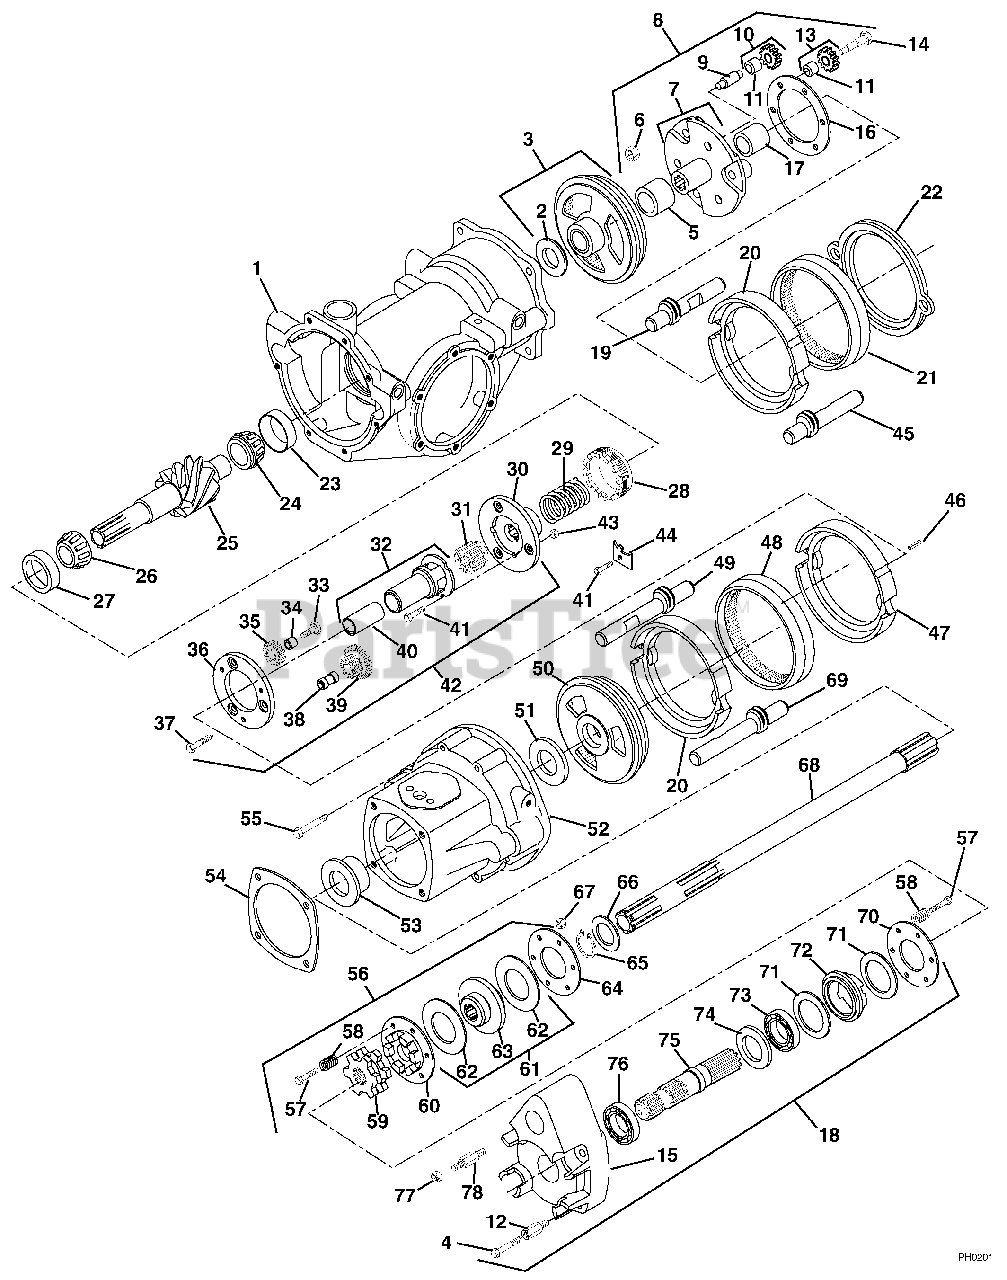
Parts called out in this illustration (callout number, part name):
1	Transmission Housing
2	Plate-Rear Thrust
3	Assembly-Ring Gear & Bushing
4	Bolt-Hex .50-13 x 1 Grade 5
5	Bushing-Sleeve 1.125 x 1.502 x 1.312
6	Nut-Locking .312-18 x .265
7	Assembly-Planet Gear Carrier
8	Assembly-Hi-Lo Planetary
9	Pin-Hi-Lo Orbit Gear
10	Assembly-Internal Orbit Gear
11	Bushing-Sleeve .500 x .627 x .465
12	Stud-Quick Hitch
13	Assembly-External Orbit Gear
14	Bolt-Orbit Gear
15	Casting-Quick Hitch
16	Spacer-Pin
17	Bushing-Sleeve .737 x .877 x .683
18	Quick Hitch Assembly
19	Rod-Rear Right Hand Clutch Slide
20	Assembly-Clutch Cup
21	Gear-Rear Ring
22	Spacer-Rear
23	Bearing-Cup 2.328 x .465
24	Bearing-Cone 1.25 x .66
25	Weldment-8-Lead Worm (114, 115, 117, 119, 307, 309, 312)
25	Weldment-4-Lead Worm (311, 313)
26	Bearing-Cone 1.250 x 2.875
27	Bearing-Cup 2.875 x .688
28	Nut-Bearing 3.00 - 16
29	Spring-Compression .188 x 1.66 x 2.0
30	Plate-Front Pin
31	Gear-Sun Pinion Spur
32	Assembly-Quill and Bushing
33	Bolt .38-24 x .860
34	Spacer .375 x .686 x .516
35	Gear-Reverse Idler Spur
36	Spacer-Front Pin
37	Bolt-Spacer .38-16 x 1.81
38	Pin-Forward Reverse Orbit Gear Steel
39	Gear-Orbit Spur
40	Bushing-Sleeve .875 x 1.002 x 2.015
41	Bolt-Hex .25-20 x .63
42	Assembly-Forward Reverse Planetary
43	Nut-Hex .250-20 Grade 2
44	Nut-Adjusting
45	Rod-Rear Left Hand Clutch Slide
46	Pin-Roll .368 x .500
47	Cup-Gear
48	Internal Spur
49	Rod-Left Hand Clutch Slide
50	Cone-Reverse Gear
51	Disk-Friction
52	Assembly-Advance Casting
53	Bushing-Flange 1.375 x 1.628 x .957 x 2.125
54	Gasket-Attachment
55	Bolt-Hex .31-18 x 3.25 Grade 8
56	Assembly-Clutch
57	Bolt-Hex .31-24 x 1.75
58	Spring-Compression .156 x .343 x .75
59	Dog
60	Plate-Dog
61	Assembly-PTO Clutch Friction Plate
62	Washer-Friction
63	Plate-Drive
64	Plate-Back
65	Ring-Retaining-External .875 x .042
66	Washer-Thrust .877 x 1.427 x .032
67	Nut-Jam .312-24
68	Shaft-Pinion
69	Rod-Right Hand Clutch Slide
70	Plate-Back
71	Disc-Brake
72	Brake-Dog Plate
73	Bearing-Ball .984 x 2.047 x .591
74	Seal 1.102 x 2.047 x .315
75	Shaft-Quick Hitch
76	Bearing-Ball .984 x 2.04 x .59
77	Nut .50-13
78	Stud-Quick Hitch
